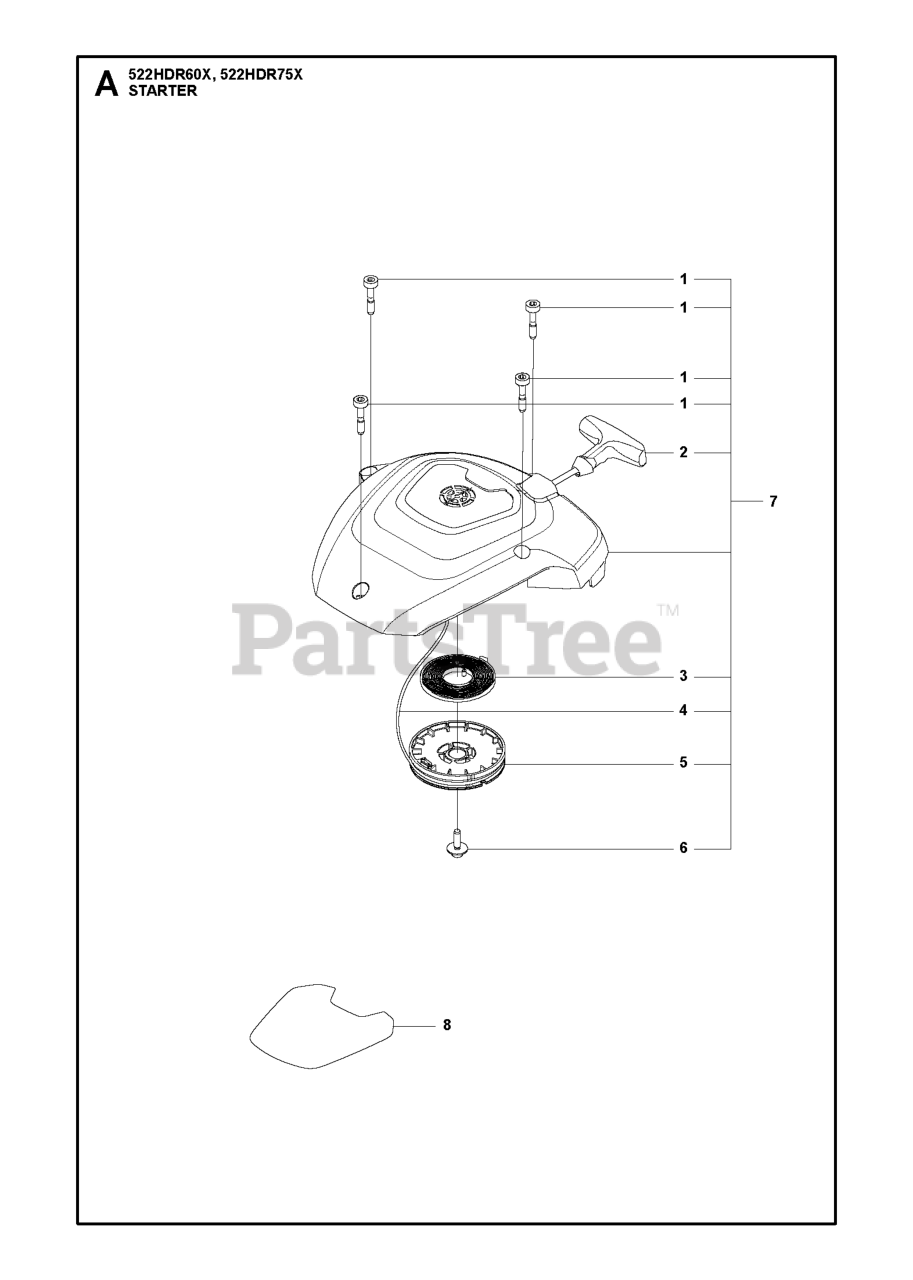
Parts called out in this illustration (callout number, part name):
1	SCREW CITXSCMO M5X25
2	STARTER HANDLE
4	STARTER CORD
5	STARTER PULLEY
6	SCREW ITXSCT PL5X16 10.9 TBO
7	STARTER ASSY 522
8	LABEL STARTER 522HDR60X
8	LABEL STARTER 522HDR75X
